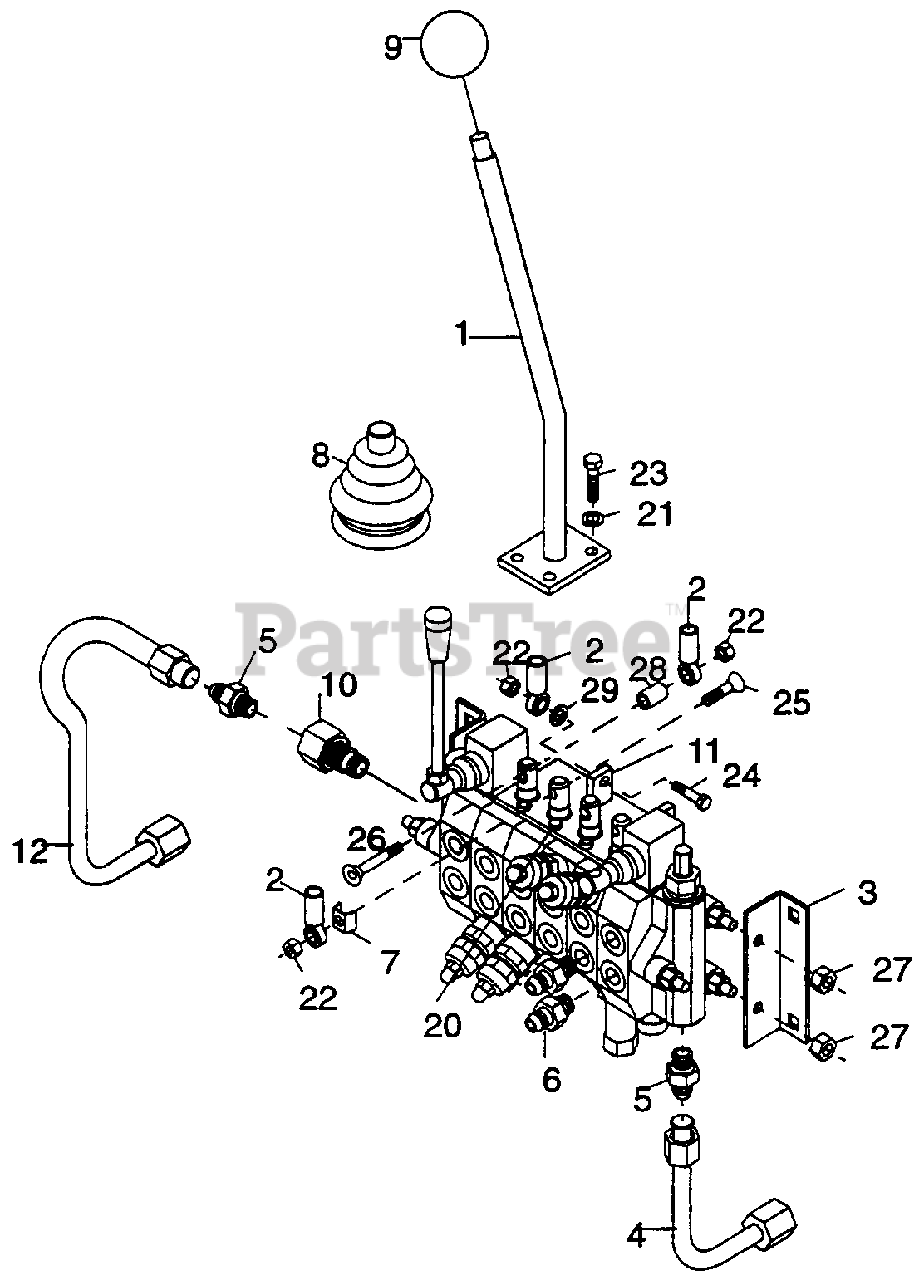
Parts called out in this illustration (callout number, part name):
1	Control handle
2	5/16 NF Female rod end
3	Valve mounting bracket
4	JIC 8F x SAE 8F Hydraulic tube assembly
5	JIC 8M x O-Ring 8M Adapter
6	9/16-18 To O-Ring connector
7	16 GA x .36 x .67 x .63 Clip
8	Rubber control boot
9	1.88 Dia. x 1.2 NC Knob
10	Power-Beyond sleeve
11	Valve linkage mount
12	Assembly hydraulic tube 3/4 SAEF JIC8F
20	5mm x .8P x 12mm Hex head cap screw
21	5/16 Standard lockwasher
22	5/16 NC Hex locknut
23	5/16 NF x 3/4 Hex head cap screw GR5
24	5/16 NC x 1-1/4 Hex head cap screw GR5
25	5/16 NC x 1-1/2 Countersunk head screw
26	5/16 x 2 Countersunk head screw
27	8mm x 1.25P Hex nut
28	.328 x .463 x .716 Sleeve
29	.328 x .50 x .093 Washer
